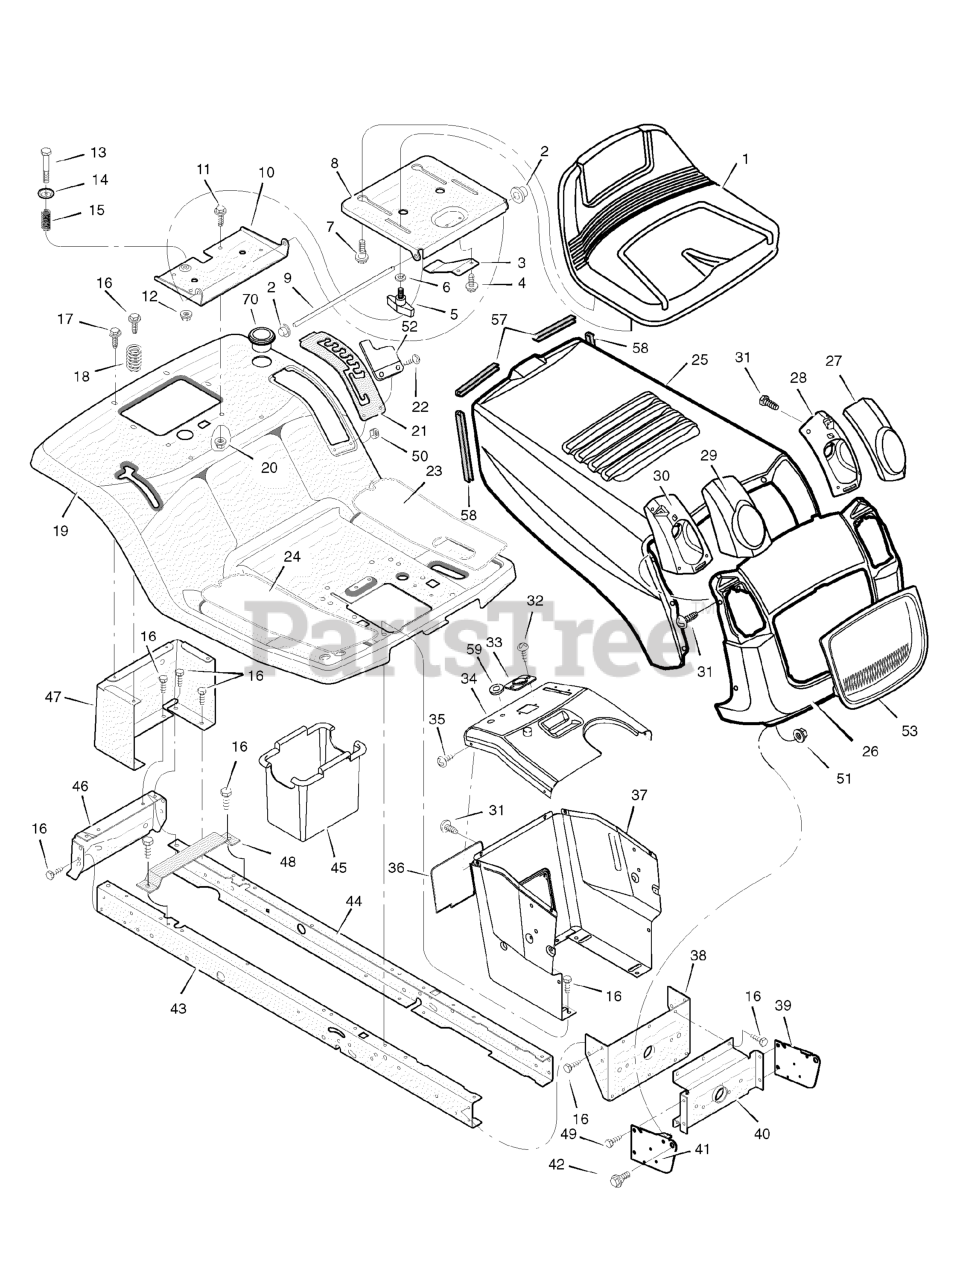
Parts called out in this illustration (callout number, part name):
1	Seat
2	Cap, Push 0n
5	Bolt, Wing
6	Washer
7	Bolt, Shoulder
8	Support, Seat
9	Rod, Pivot
10	Bracket, Pivot
11	Bolt
13	Bolt, Shoulder
20	Nut
21	Plate, Index
23	Mat, Left
24	Mat, Right
27	Lens, Left
28	Housing, Left Headlamp
29	Lens, Right
30	Housing, Right Headlamp
33	Bearing, Steering
34	Dash
36	Panel, Access
37	Support, Dash
38	Bracket, Rear Hanger
39	Support, Left Grille
40	Axle, Hanger
41	Support, Right Grille
42	Bolt, Shoulder
43	Frame, Right
44	Frame, Left
45	Container, Battery
46	Plate, Hitch
47	Panel, Rear
48	Support, Battery
52	Cover, Lift Detent
53	Insert, Grille
57	Trim, Hood (3.75")
58	Trim, Hood (6.5")
59	Grommet, Parking Brake
70	Holder, Cup
